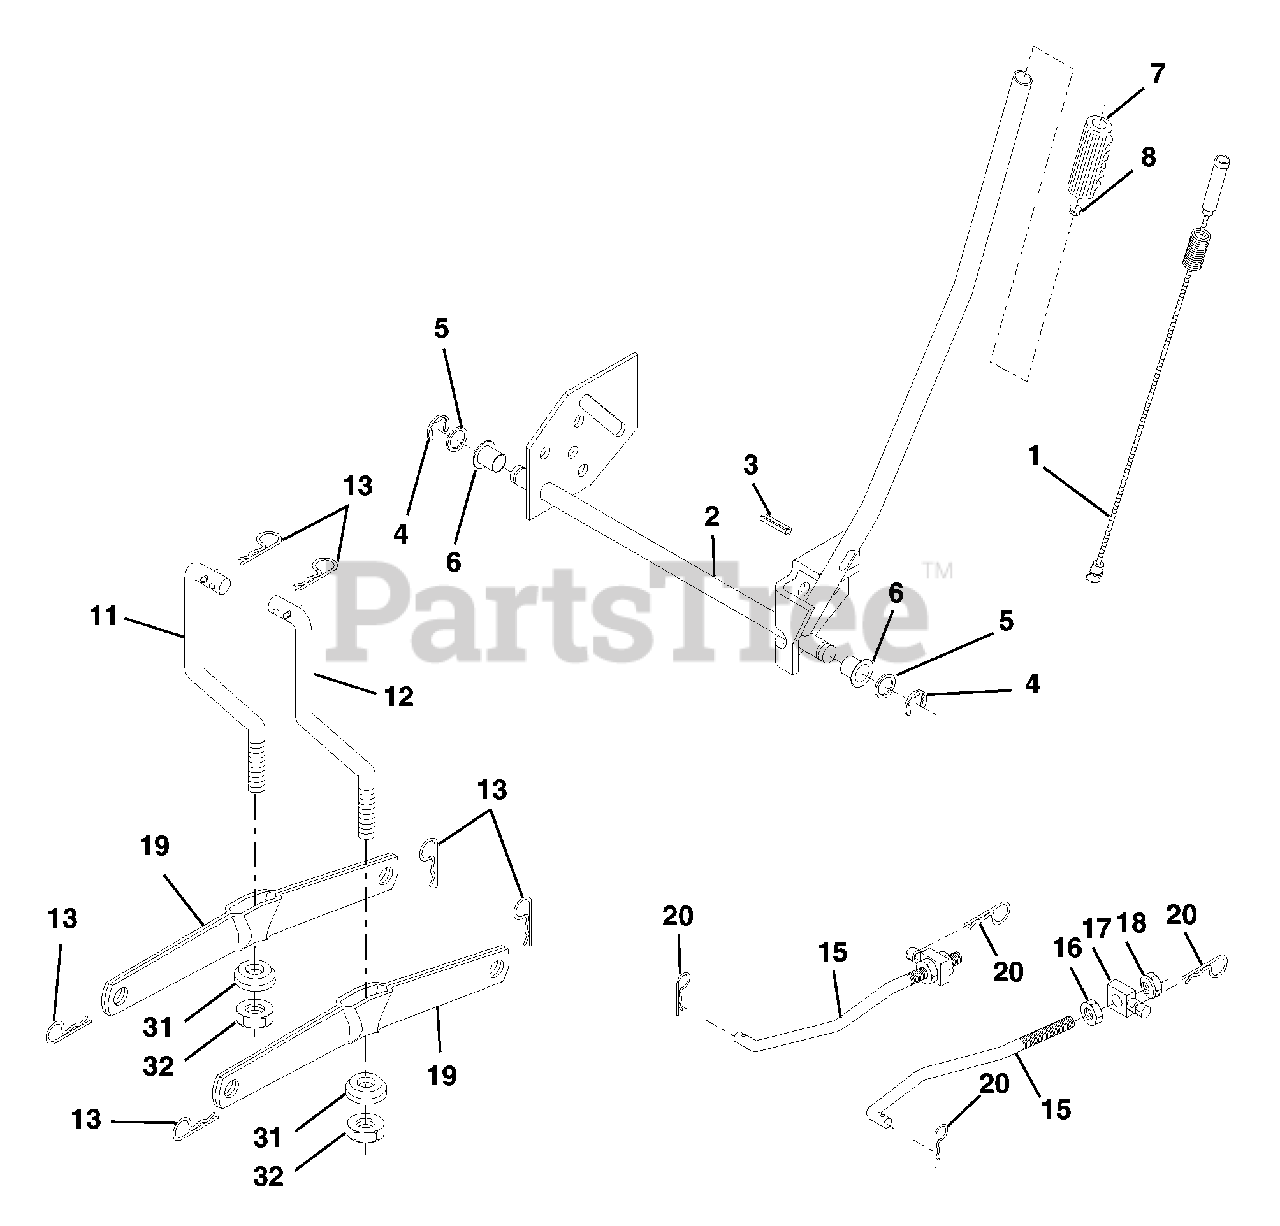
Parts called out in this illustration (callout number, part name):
1	Lift Lever Inner Wire Assembly
2	Shaft Assembly, Lift
3	Pin, Groove
5	Washer 21/32 x 1 x 21 Ga.
6	Bearing, Nylon
7	Grip, Handle
8	Button, Plunger, Red
11	Link, Lift, L.H.
12	Link, Lift, R.H.
13	Retainer Spring
15	Link, Front
16	Nut, Hex, Jam 1/2-13 unc
17	Trunnion
18	Locknut, Hex, with Washer Insert 1/2-13 unc
19	Arm, Suspension, Rear
20	Retainer Spring
31	Bearing, Pvt, Lift
32	Nut, Crownlock 3/8-24
